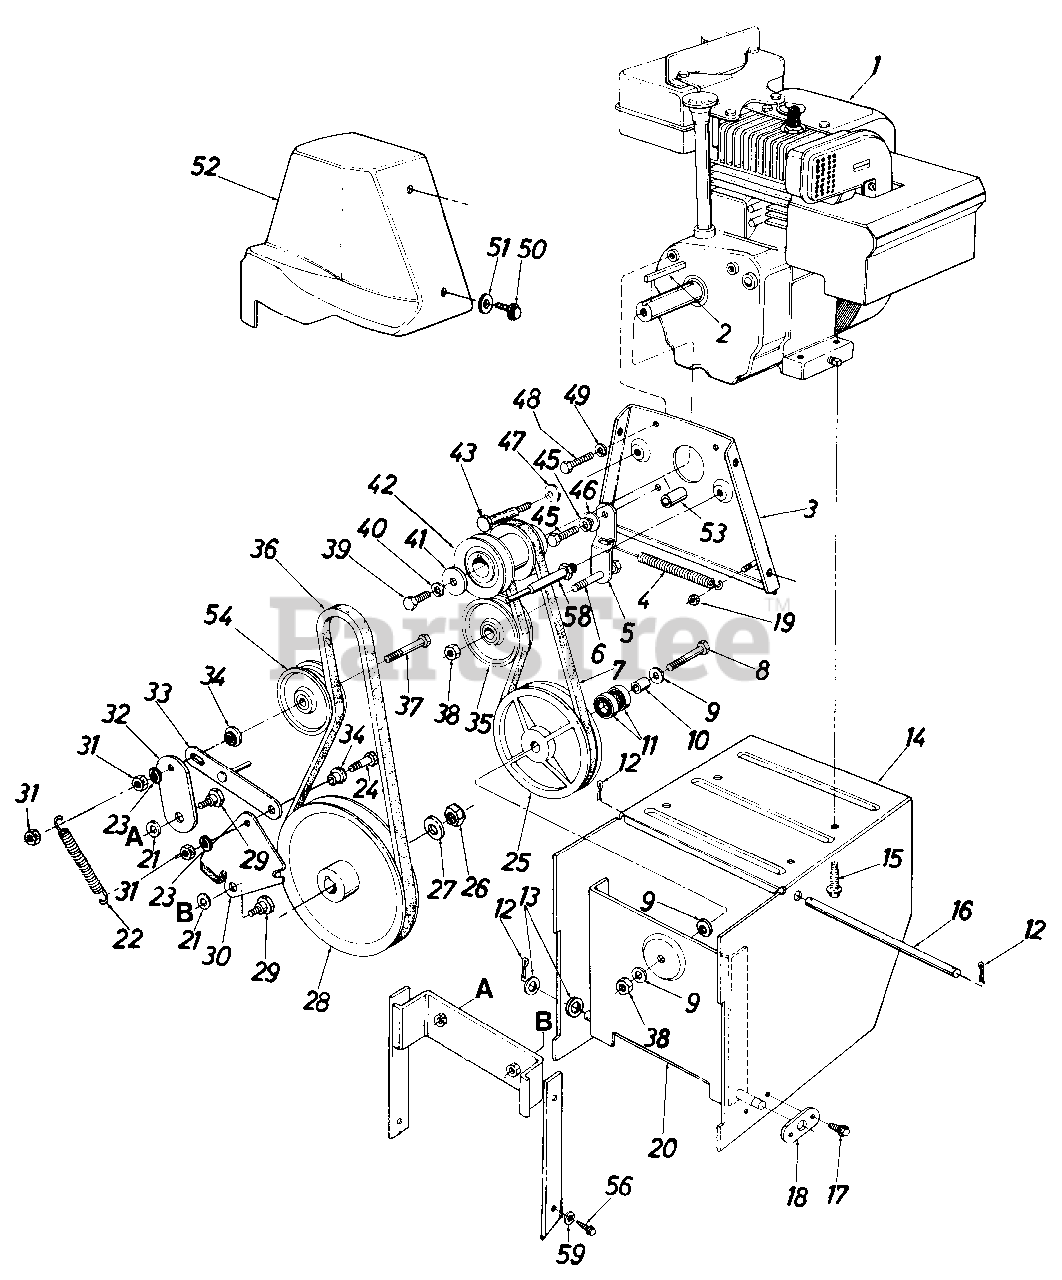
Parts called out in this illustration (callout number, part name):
1	Engine
2	Sq. Key 3/16" x 1.50" Lg.
3	Engine Plate Ass'y.
4	Extension Spring .50" O.D. x 3.97" Lg.
5	Drive Clutch Idler Brkt.
6	Hex Bolt 3/8-24 x 1.25" Lg.*
7	V"-Belt
8	Hex Bolt 3/8-24 x 1.50" Lg.
9	Bell-Wash. .40" I.D. x .88" O.D. x .06
10	Spacer .38" I.D. x .62" O.D. x.75" Lg.
11	Ball Brg. .62" I.D. x 1.38" O.D. x .44
12	Cotter Pin 3/32" Dia. x .75" Lg.*
13	Fl-Wash. .53" I.D. x 1.00" O.D. x .125
14	Frame Ass'y.
15	Hex Wash. Hd. Self-Tap Scr. 3/8-16 x 1.25" Lg.
16	Shaft .50" Dia. x 9.50" Lg.
17	Hex Wash. Hd. Self-Tap Scr. 1/4-20 x .50" Lg.
18	Axle Bracket
19	Hex L-Nut 1/4-20 Thd.
20	Drive Pulley Support Brkt. Ass'y.
21	Bell-Wash. .40" I.D. x 1.13" O.D.
22	Extension Spring .56" O.D. x 4" Lg.
23	L-Wash. 3/8" I.D.*
24	Hex Scr. 3/8-16 x 1.25" Lg.
25	6.00" O.D. Drive Pulley Ass'y.
26	Hex Jam Cent. L-Nut 5/8-18 Thd.
27	Fl-Wash. .64" I.D. x .94" O.D. x .06
28	1/2" V-Pulley .625" I.D. x 7.50" O.D.
29	Shld. Bolt .625" Dia. x .170" Lg.
30	Brake Bracket Ass'y.
30	Brake Brkt. Ass'y.
31	Hex Ins. L-Nut 3/8-16 Thd.
32	Auger Clutch Idler Brkt.
33	Brake Linkage Ass'y.
34	Shld. Spacer .625" I.D.
35	Fl-ldler Pulley 2.25" O.D.
36	V-Belt
37	Hex Bolt 3/8-16 x 2" Lg.*
38	Hex Ins. Jam L-Nut 3/8-24 Thd.
39	Hex Bolt 3/8-24 x 1.50" Lg.
40	L-Wash. 3/8" I.D.*
41	Bell-Wash. .40" I.D. x 1.25" O.D.
42	Double Groove Engine Pulley
43	Shld. Scr. .498" x 3.0" Lg.
43	Hex Bolt 5/16-24 x 1.00"-Lg.*
45	L-Wash. 5/16" I.D.*
46	Shld. Spacer .320" I.D.
47	Bell-Wash. .40" I.D. x .88" x .06
48	Hex Bolt 5/16-24 x .62" Lg.
49	L-Wash. 5/16" I.D.*
50	Hex Wash. Hd. Self-Tap Scr. 1/4-20 x .50" Lg.
51	Fl-Wash. .28" I.D. x .75" O.D. x .06
52	Belt Cover
53	Spacer
54	Fl-ldler Pulley 2.75" O.D.
56	Hex Wash. Hd. Self-Tap Scr. 3/8-16 x .75" Lg.
56	Ignition Key
58	Stud 3/8-16 x 3.37" Lg.
59	L-Wash. 3/8" I.D.-H.D.
